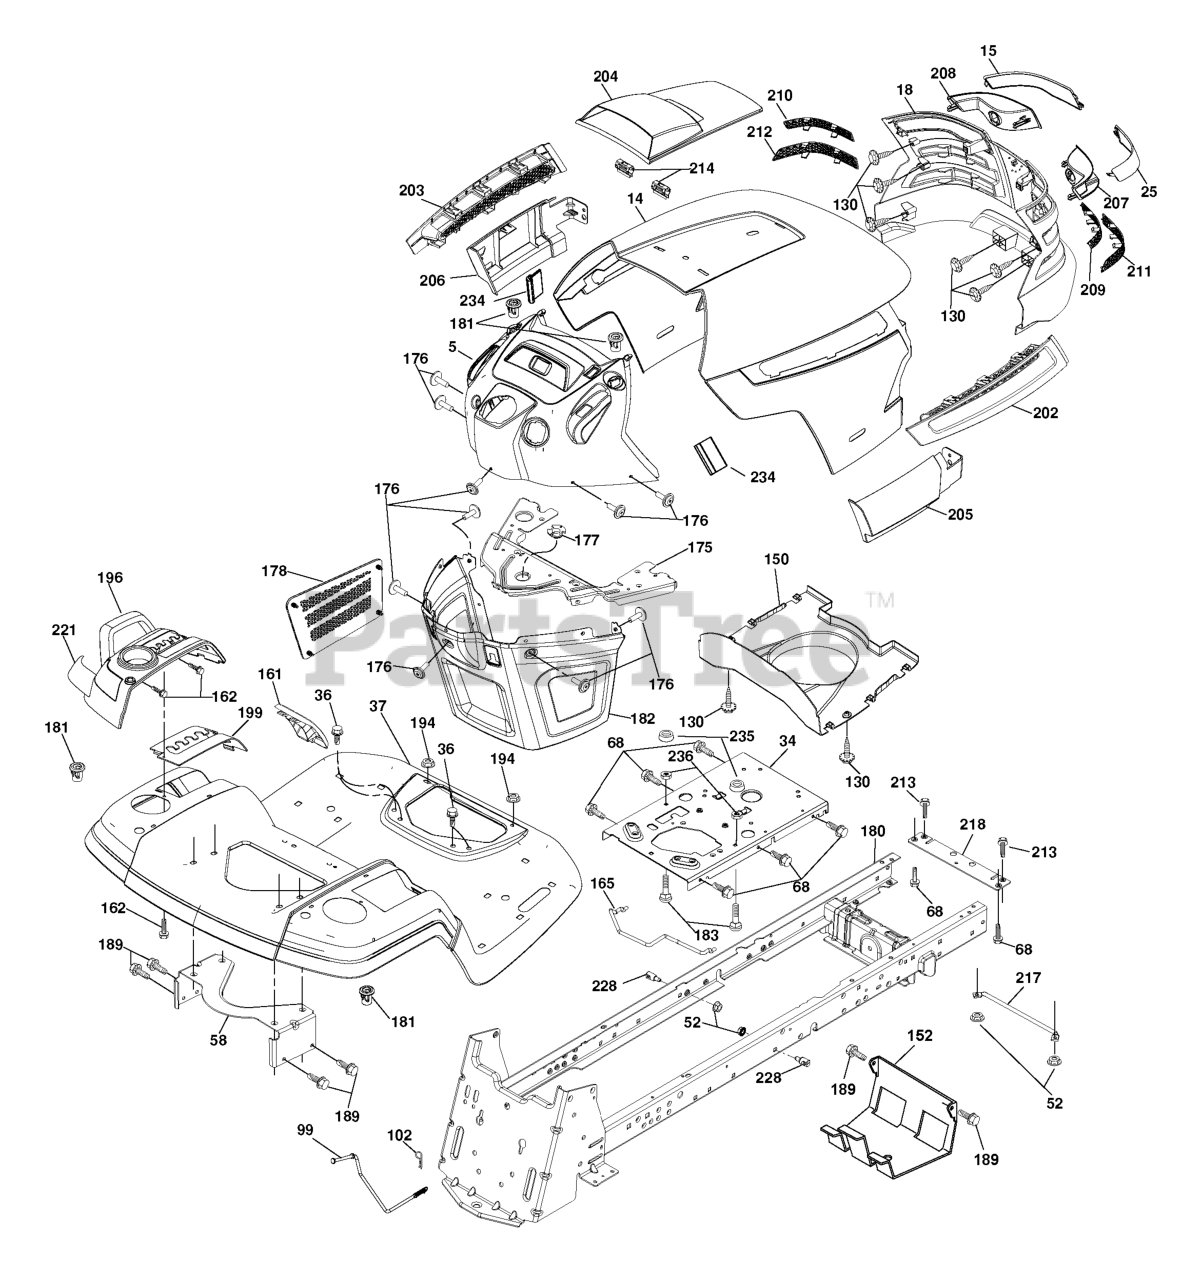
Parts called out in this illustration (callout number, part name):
5	DASH.ASM.HUSQ.GT.E.RECT.W/CK
14	HOOD.PNT.HUSQVARNA.GT.
15	LENS.LH.TEX.GT.HUSQ.CL
18	GRILLE.ASM.TX.GT.HUSQ
25	LENS.RH.TEX.GT.HUSQ.CL
34	PLATE.ENGINE.WELDED.CHASSIS
36	SCREW 5/16"
37	FENDER.PNT.TX.GT.CH/FW.ORANGE
52	LOCKNUT
58	BRKT.SUPPORT.FNDR/TANK
68	Screw 5/16-18 x 1/2
99	ROD ASM BYPASS
102	RETAINER M
130	SCREW
150	AIR.DUCT.HOOD.TEX.GT.HUSQ
152	SHIELD.BROWNING.W/TEX
161	CONSOLE.FUEL.WINDOW.HU
162	SCREW.HI-LO.CONSOLE
165	SUPPORT.TANK.REAR.W/TEX
175	PLATE.CROSSMEMBER.HUSQ
176	RP SCREW.10-24X5/8.WSHD
177	BUSHING, STEERING
178	CARGO.ASM.NET.TXGT.W/C
180	CHASSIS.WLDMT.TX.GT.05
181	BUSHING.MNT.FEND.CRGO.
182	DASH.LOWER.COMMON.12V.
183	BOLT.5/16-18X1-1/4 FULL.THREAD
189	SCREW
194	NUT.71038.31-18.HEX.NYLOCK
196	RP CONSOLE.ASM.DECKLFT.W/
199	PLATE.DECK.LIFT.HUSQVARNA.GT
202	VENT.SIDE.HOOD.HUSQ.RH.GREY
203	VENT.SIDE.HOOD.HUSQ.LH.GRAY
204	VENT.TOP.HOOD.HUSQVARN
205	SKIRT.HOOD.SIDE.HUSQ.RH.GREY
206	SKIRT.HOOD.SIDE.HUSQ.LH.GREY
207	BEZEL.RH.TEX.GT.HUSQ
208	BEZEL.LH.TEX.GT.HUSQ
209	INSERT.HEX.GRILL.HUSQ.GREY
210	INSERT.HEX.GRILL.HUSQ.
211	INSERT.HEX.GRILL.HUSQ.
212	INSERT.HEX.GRILL.HUSQ.
213	BOLT
214	CLIP.RETAINER.TINNER.
216	SCREW, 5/16-18 X 1/2
217	ROD PIVOT CHASSIS/HOOD
218	X-PIECE.HOOD.STOP.NON/
219	STUD.FASTNER.W/ANTI-ROTATE
220	LOCKNUT-FLANGE 5/16-18
221	REFLECTOR.LH.TEX GT HU
228	STUD.FASTNER.W/ANTI-ROTATE
234	BUMPER.HOOD.TEX.HUSQVARNA
235	SPACER FENDER
236	NUT.CENTERLOCK.5/16-
